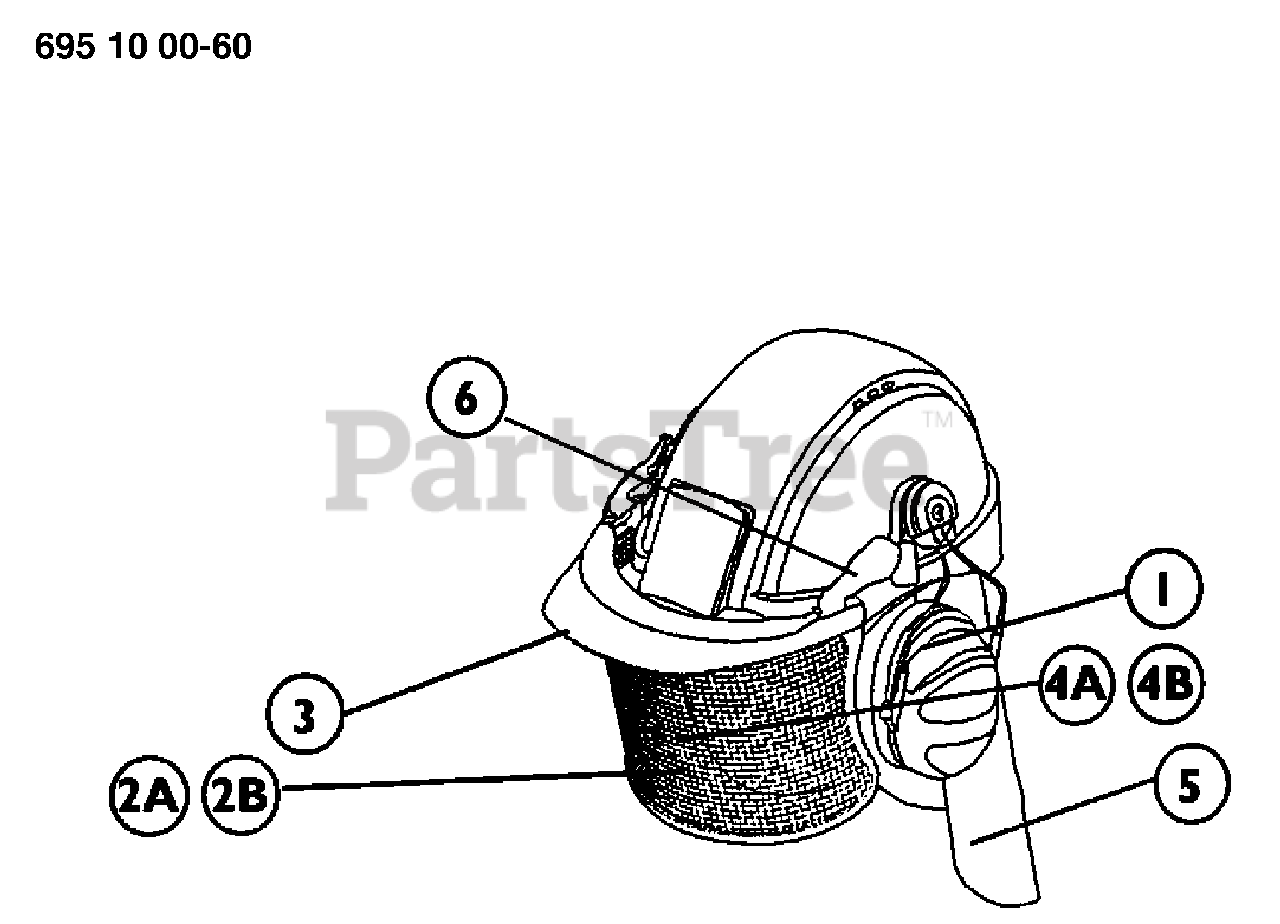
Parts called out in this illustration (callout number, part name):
1	Hearing protector set w/ attachments for helmet
2A	Metal mesh visor with attachments
2B	Nylon mesh visor with attachments
3	Replacement brim
4A	Metal mesh screen only
4B	Plexiglass visor only
5	Rain shield
6	Pair of replacement linkage arms for face screen
695100060	Helmet System
